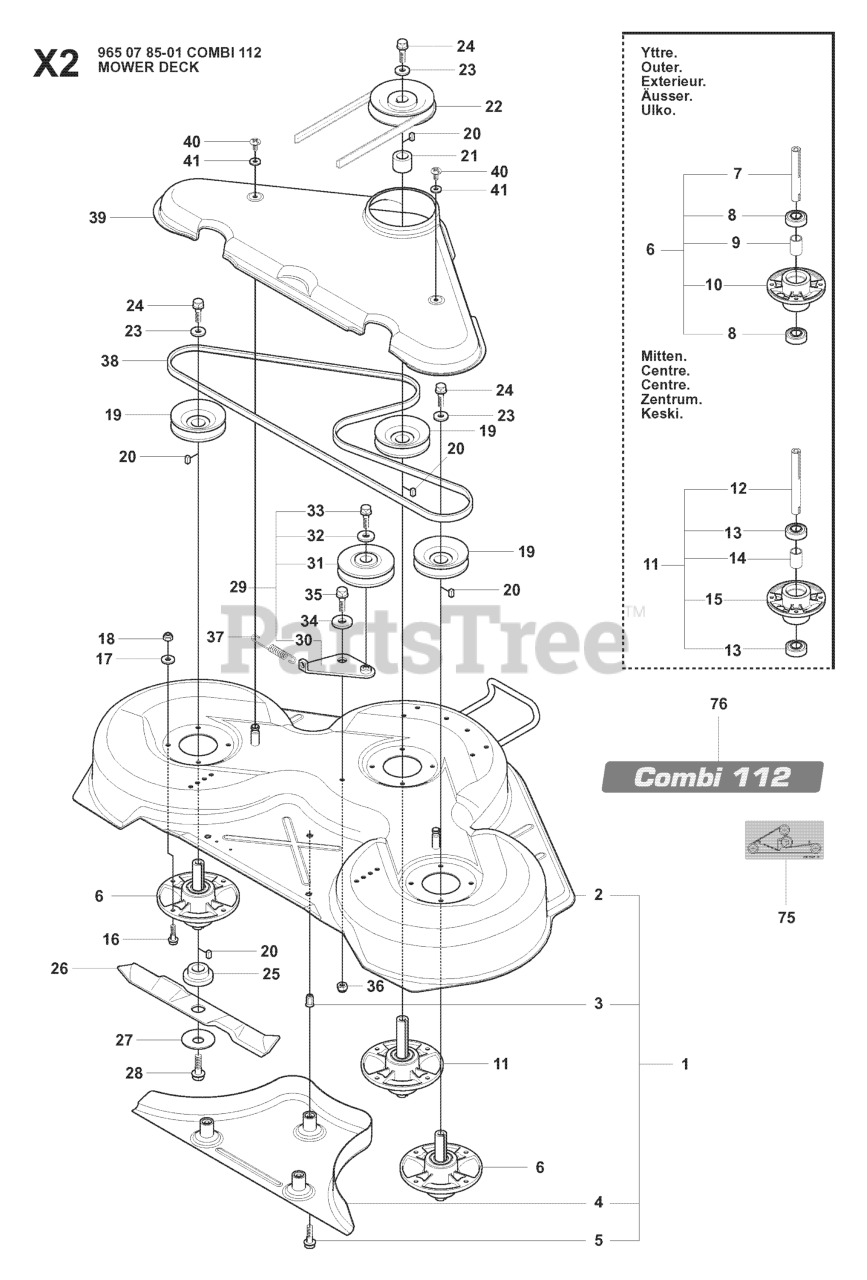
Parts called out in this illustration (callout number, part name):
1	CUTTING DECK C112 GREY RIDER
2	CUTTING DECK ASSY C112 GREY
6	RP SPINDLE ASSY
10	BEARING HOUSING
11	SPINDLE ASSY
15	BEARING HOUSING
17	WASHER BRB 8.4X17
18	LOCKNUT M8
27	WASHER
29	BELT TENSIONER ASSY
30	BELT TENSIONING ARM
34	WASHER
36	LOCKNUT M8
38	BELT
39	BELT COVER
